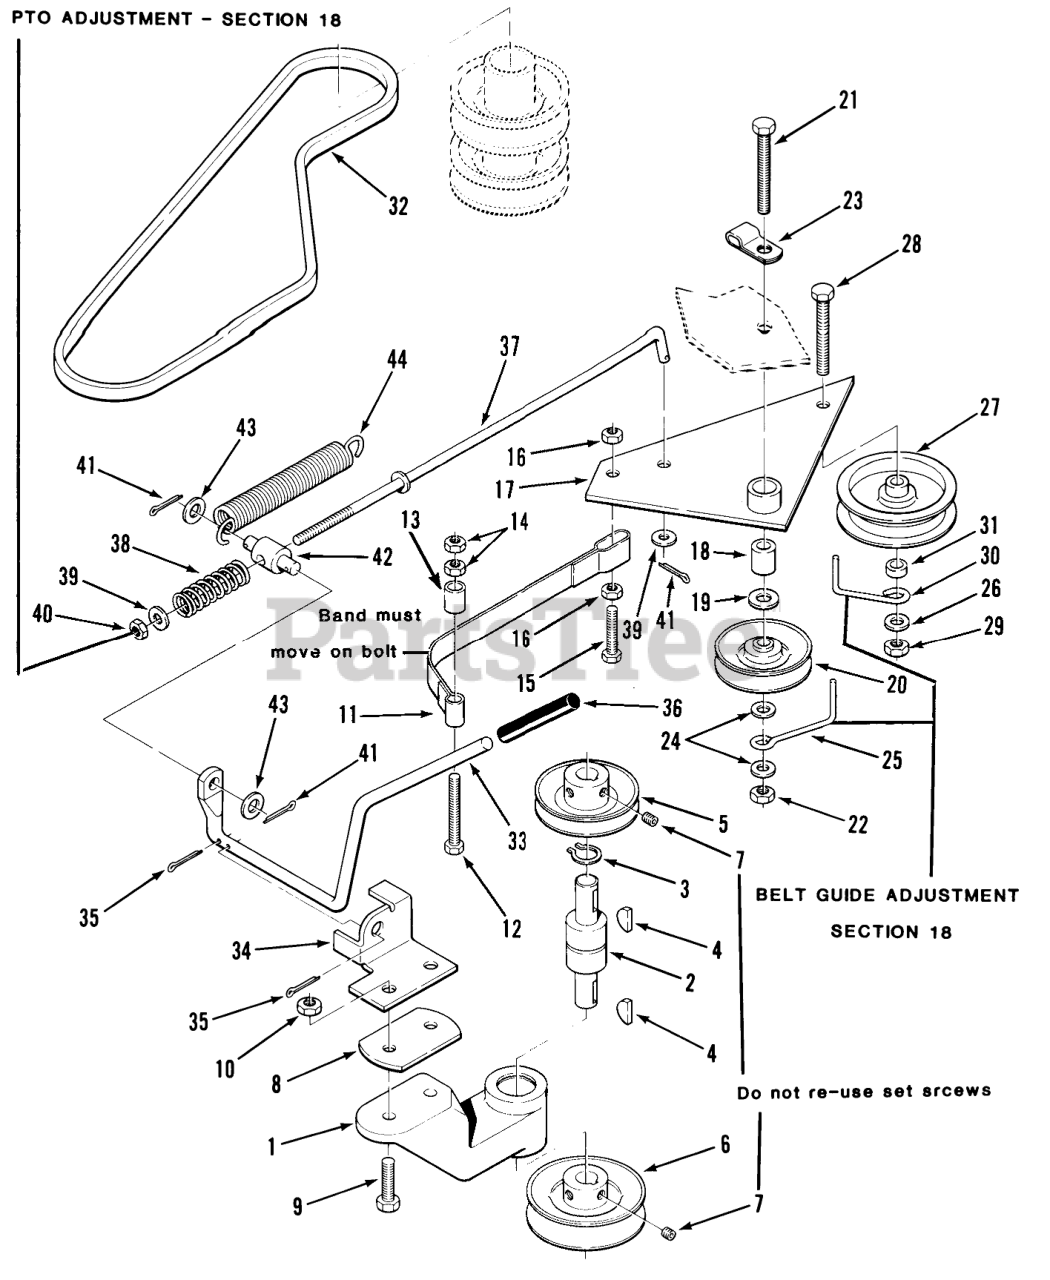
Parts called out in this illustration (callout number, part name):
2	BEARING-INT SHAFT
4	KEY-WOODRUFF
5	PULLEY
6	PULLEY
32	V-BELT
36	GRIP
38	SPRING-CLUTCH
39	WASHER 5/16 SAE
44	SPRING *R
